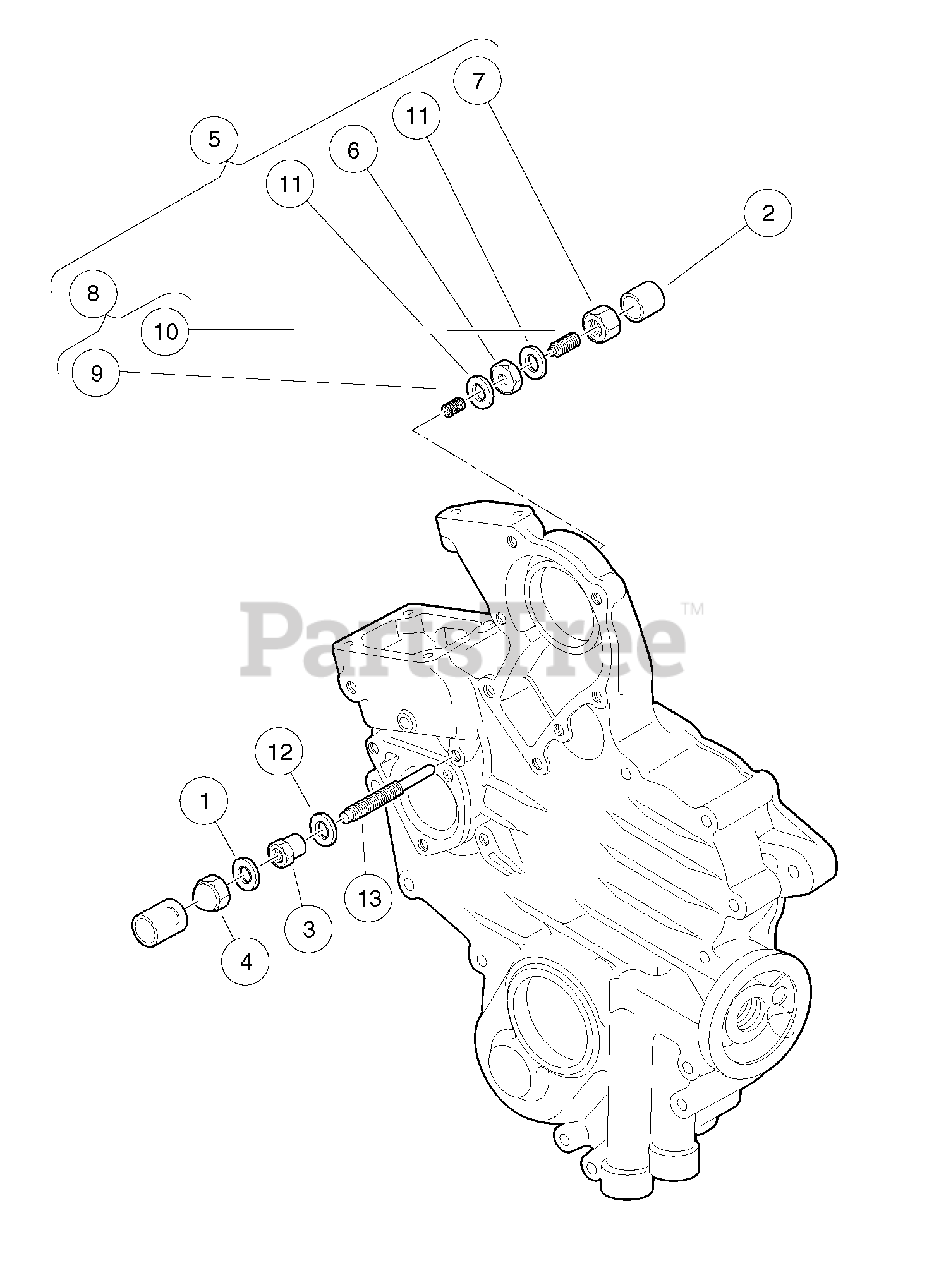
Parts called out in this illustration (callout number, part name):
1	Gasket, 6 X 10
2	Cap, Bolt Assy
3	Nut, Lock, Special
4	Nut, Special
5	Assy, Idle Apparatus
6	Nut, M8, D722 Idle App, Specl
7	Nut, M8, D722 Idle App
8	Assy, Bolt, Adjusting
9	Spring, Idle Apparatus
10	Stud, Idle Adjustment
11	Gasket, Idle Apparatus, Rear
12	Gasket, Idle Apparatus, Front
13	Bolt, Idle Adjusting
